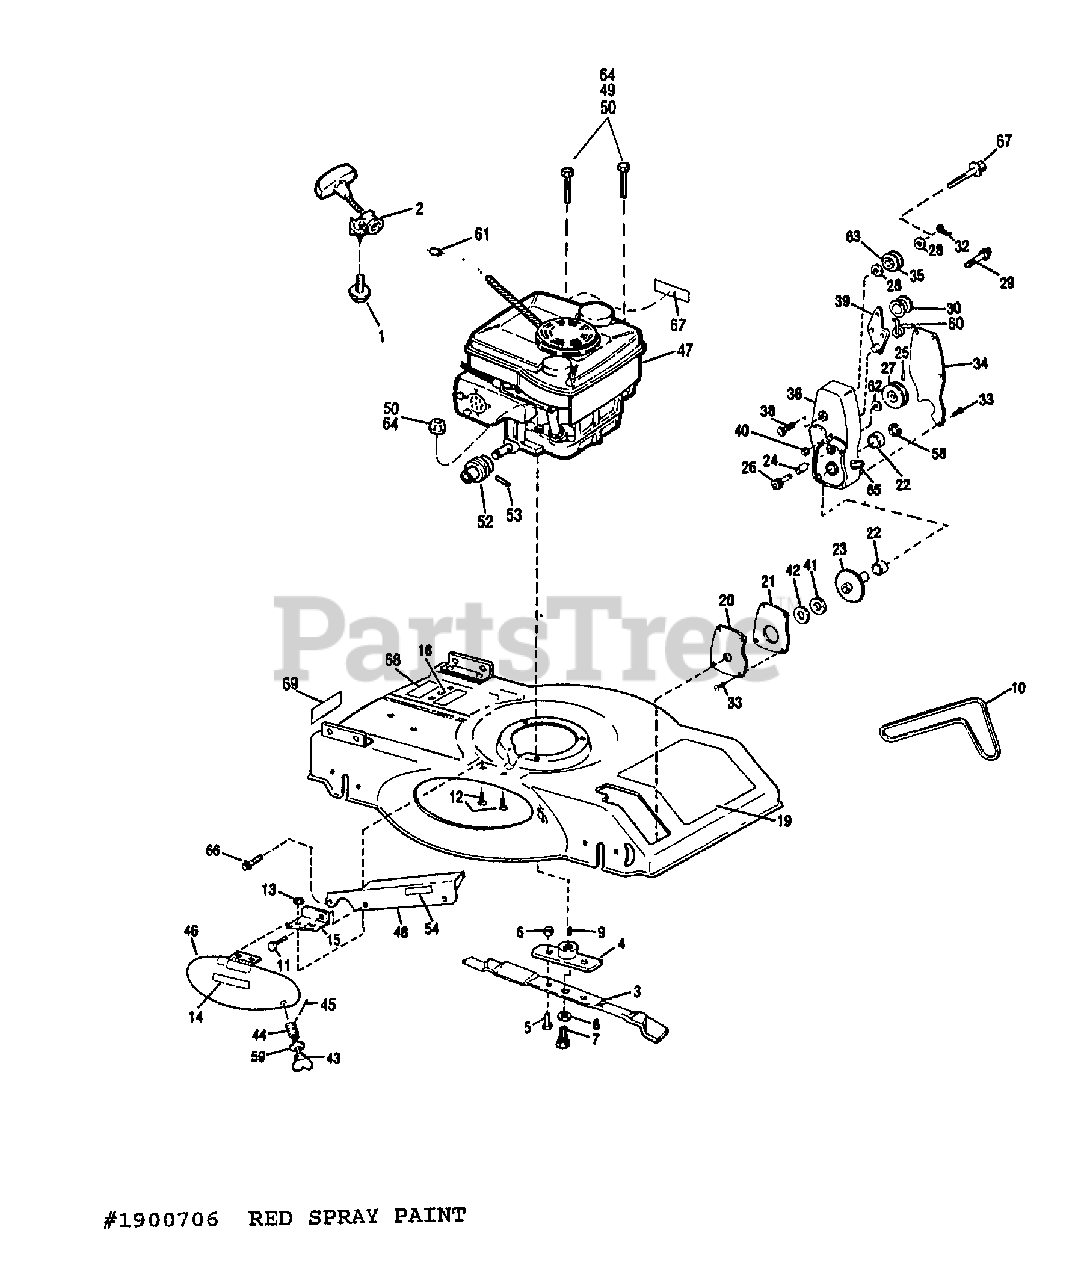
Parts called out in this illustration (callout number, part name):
1	SCR-HFLK {NOT 8656}
2	GUIDE-ROPE {NOT 8656}
3	BLADE-22" MULCHER
4	ASSM-BLADE COUPLING
5	SCR-HH 3/8-16X1.0 G5 ZP
6	NUT-LOCK 3/8-16
7	SCR-SHOULDER
8	WASHER-LK .5
9	KEY-WOODRUFF
10	BELT-DRIVE
11	SCR-SHOULDER
12	SCR-CARR 1/4-20X.375
13	NUT-HF/LK 1/4-20 ZP
14	DECAL-CAUTION
15	BRKT-SUPPORT
18	DECAL-CUTTING HEIGHT
19	DECAL-LOGO
20	COVER-GEAR CASE BOTTOM
21	GASKET-GEAR CASE
22	BEARING-BRONZE
23	ASSM-GEAR SHAFT
24	BEARING-BRONZE
25	PIN-DRIVE .218X1.12
26	ASSM-STEEL PINION SHAFT
27	SHEAVE
28	FLAT WASHER
28	WASHER-FLAT 1.0X.516X.031 (A)
29	SCR-HH 3/8-16X1.0 G5 ZP
30	IDLER-FLAT
32	COTTER PIN, 1/8 X 3/4 (A)
32	PIN-COTTER .125 X .75 ZP
33	SCR-HW M10-24X.5 STH ZP
34	COVER-GEAR CASE TOP
35	SHEAVE
35	KIT-IDLER PULLEY (A)
35	SHEAVE (B)
36	KIT-GEAR CASE
38	SCR-SHOULDER
39	ASSM-IDLER ARM
40	NUT-PUSH 3/8 ZP
41	WASHER-1.5X.755X.062
42	WASHER-FELT
43	PIN-CHUTE LOCK
44	SPRING-COMPRESSION
45	PIN-ROLL .093 DIAX.62
46	COVER-DISCHARGE W/DECAL (INCL. REF. NO. 14)
47	BRIGGS & STRATTON ENGINE, 4.0 HP, 122782
47	BRIGSS & STRATTON ENGINE, 5.0 HP, 124782
47	BRIGGS & STRATTON ENGINE, 5.0 HP, 124787
48	ASSM-BELT COVER
49	SCR-HH 5/16-18X1.25 G5ZP
50	HEX TOPLOCK NUT
50	NUT-TOP/LK 5/16-18 ZP (A)
52	SHEAVE
53	PIN-ROLL
54	DECAL-FRONT WHEEL DRIVE
58	RING-GRIP EXT .5 ID
59	WASHER-.75X.312X.065 ZP
60	SPRING-TORSION
61	STOP-STARTER ROPE {NOT 8656}
62	WASHER-SHIM
63	BALL BEARING
63	BEARING-BALL (A)
64	HEX HD. CAPSCREW, THD. FORMING, 3/8-16X1
64	SCR-HH 5/16-18X2.25 G5ZP (A)
64	SCR-HH 3/8-16X1.0 THDFM (B)
65	FITTING-GREASE 1/4-28X2.00
66	SCR-FLANGE 1/4-20X3/4 GR5
67	HEX HD. CAPSCREW, 5/16-18 X 7/8
67	SCR-HH 5/16-18X.875 G5 ZP (A)
68	DECAL-U.S.A.
69	DECAL-SOUND LEVEL
70	DECAL-ENGINE (SEARS) {RS}
